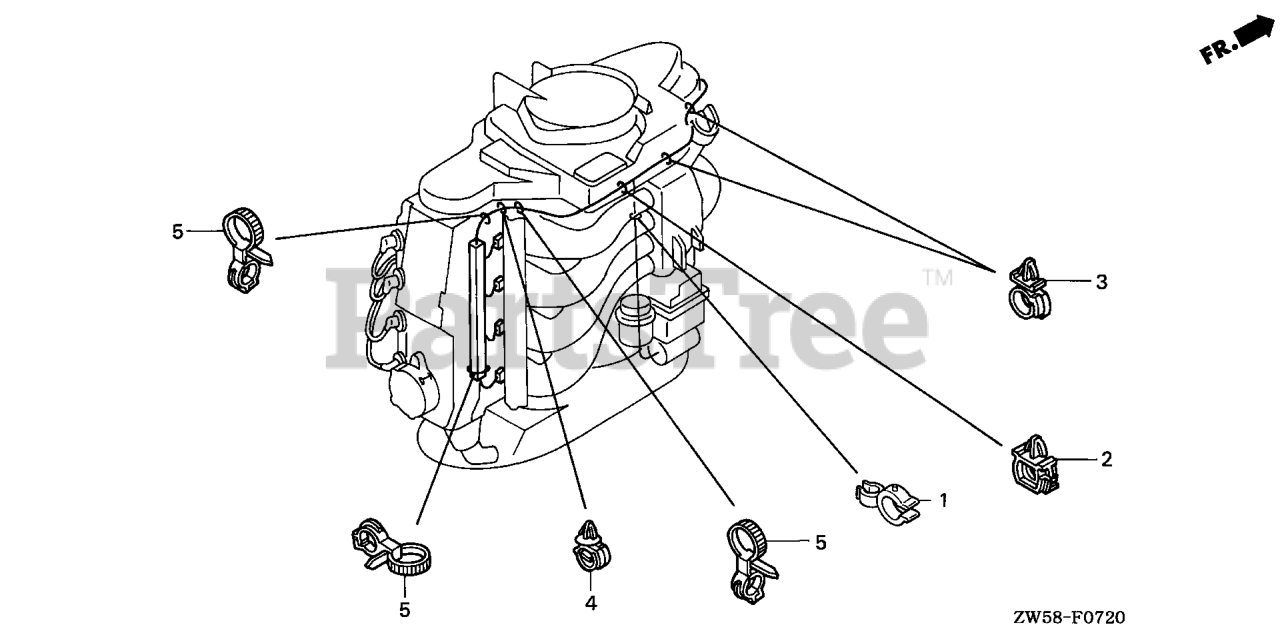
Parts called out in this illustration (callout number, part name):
1	CLIP, SHIFT WIRE
2	CLIP, WIRE HARNESS (10MM)
3	CLIP, WIRE HARNESS
4	CLIP, HARNESS
5	CLIP, TUBE (135MM) (BLACK)
